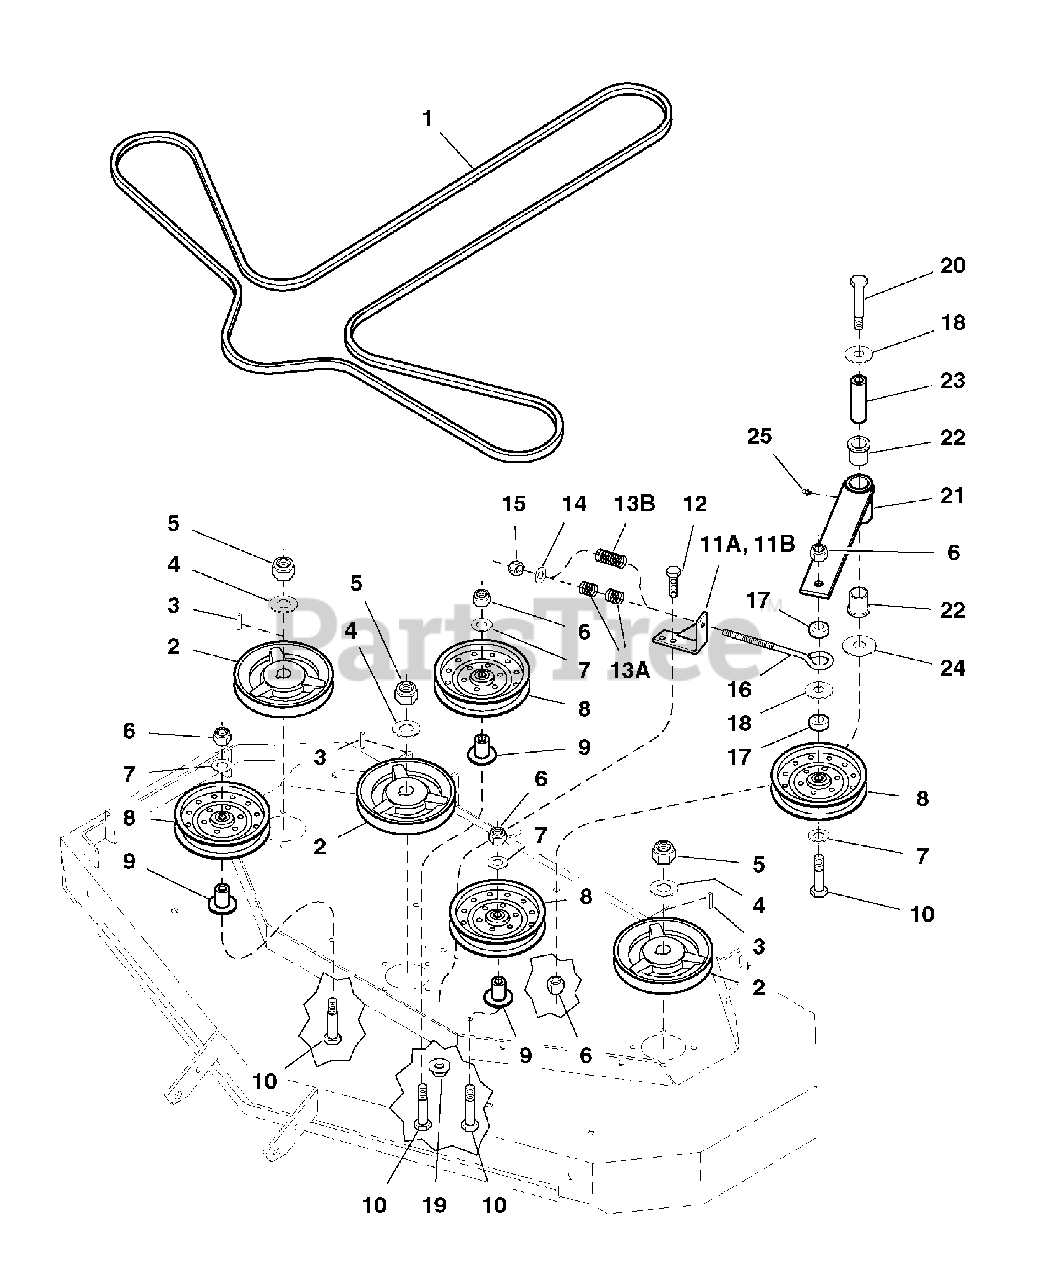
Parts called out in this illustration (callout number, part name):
1	BELT, 5V, 175.90EL, LG ARAMID, WRPD, RC
2	SPINDLE PULLEY
3	KEY, 1/4 x 1-1/4
4	WASHER, Spring
5	NUT, Hex, Nylon Lock, 5/8-18
6	NUT, Hex, Nylon Lock, 1/2-13
7	WASHER, 1/2
8	*PULLEY, FLAT IDLER, 6-3/4"
9	IDLER PULLEY MOUNT
10	CAPSCREW, Hex Hd, 1/2-13 x 3
11A	SPRING ANCHOR (S/N 201-745)
11B	SPRING ANCHOR (S/N 746 & up)
12	CAPSCREW, Hex Hd, 3/8-16 x 1
13A	SPRING, Compression (S/N 201-380)
13B	SPRING, Compression (S/N 381 & up)
14	WASHER, 3/8
15	NUT, Hex, Nylon Lock, 3/8-16
17	IDLER SPACER
18	WASHER, USS, 1/2
19	NUT, Hex, Serrated Flange, 3/8-16
20	CAPSCREW, Hex Hd, 1/2-13 x 4-1/2
21	IDLER ARM
22	BUSHING, Flange
23	IDLER ARM PIVOT SHAFT
24	WASHER, 5/8
25	GREASE FITTING
